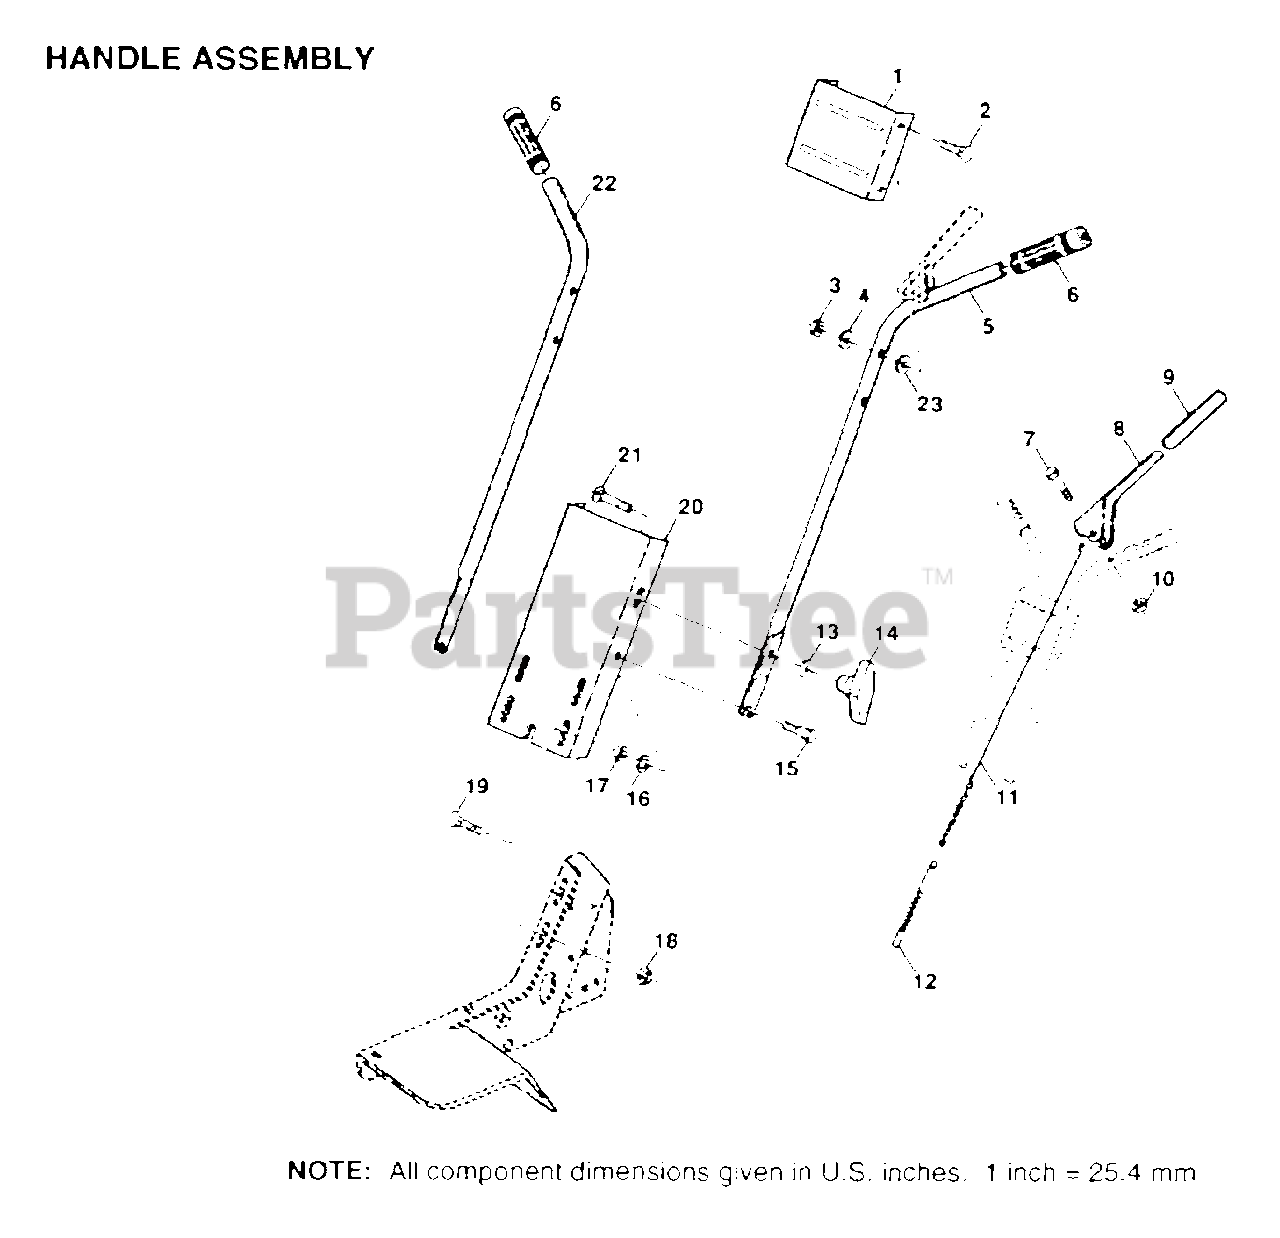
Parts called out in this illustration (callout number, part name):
1	BRKT. HANDLE
2	BOLT
4	WASHER
7	BOLT.HEX.5/16-1.5
9	GRIP T
12	SPRING EXT TI
13	WASHER
14	KNOB HANDLE
16	LOCKWASHER
17	NUT.HEX.5/16-18
18	NUT
19	BOLT
20	"PANEL, HANDLE"
21	BOLT
23	WASHER
